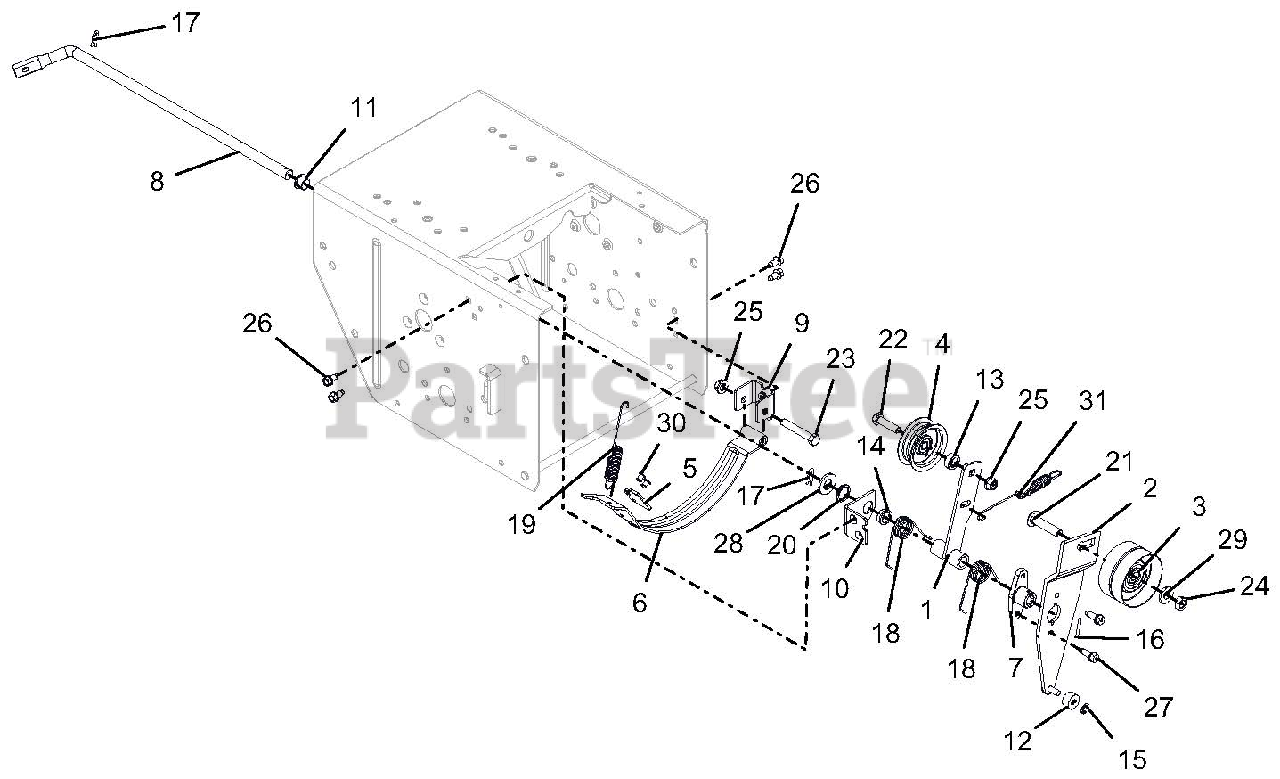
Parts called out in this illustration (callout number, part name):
1	ARM, IDLER-TRACTION
2	ARM, IDLER-ATTACHMENT
3	IDLER, FLAT-2.75 OD X .375 ID
4	IDLER, FLAT - 2.00"
5	PAD, BRAKE
6	ARM, BRAKE-ATTACHMENT
7	HUB, BRAKE ARM
8	ARM, ATTACHMENT
9	PIVOT, BRAKE
10	BRACKET, SUPPORT
11	BUSHING, POLYLINER-.50 SPLIT
12	BSHG,SLV .265 X .625 X .375
13	SPCR, BRG .315X.500X.358X.281
14	BSHG,FLANGE .500X.625X.270X.75
15	RG-RTNG-EXT .250X.010
16	PIN-ROLL .125X1.00
17	CLIP, SPRING
18	SG-TORS .067X.88
19	SG-TENS .056X.60X4.40
20	WAVE SPRING .600X.875X.25FH
21	@BLT-RHDSSQNK .38-16X1.75 G5YZ
22	@BLT-HEX .31-18X1.25 GR5 YWZC
23	@BLT-HEX .31-18X2.00 GR5 YWZC
24	@NUT-LK-CTR-JAM .375-16 YWZC
25	@NUT-LK-TOP-FLG .31-18 YWZC
26	SCR-TAP .25-20X.50 HWH TR YWZ
27	SCR-TAP-PM .25-20X.75 TR YWZ
28	@WSHR-FL-STL.531X1.06X.095YWZC
29	@WSHR-FL-STL.38X.875X.083 YWZC
30	RVT-POP .187 YZ
31	SG-TENS .06X.482X5.35
